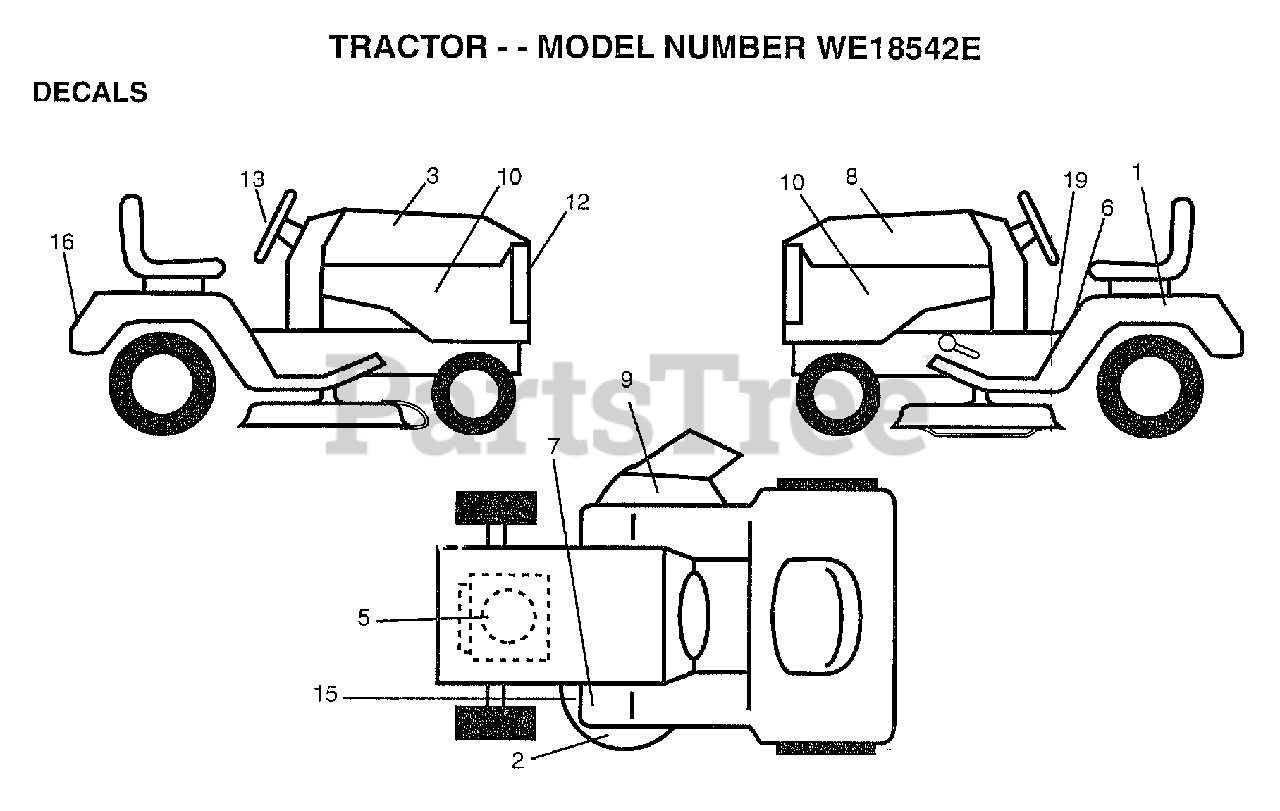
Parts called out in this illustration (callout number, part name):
1	DECAL.BATRY.3-3908
2	DECAL, DECK GRASSEATER
3	DECAL.HOOD.RH.
5	DECAL.HP.ENGINE
6	DECAL.CAUT.ENG/FR
7	DECAL T
8	DECAL.HOOD.LH
9	"DECAL, WARNING"
10	DECAL.PNL.SIDE
12	DECAL, GRILLE LENS
13	DECAL, INS STRG WH
15	"DECAL-SCHEM,BELT"
16	DECAL.FENDER.LOGO
19	"DECAL.OPER,SDL"
